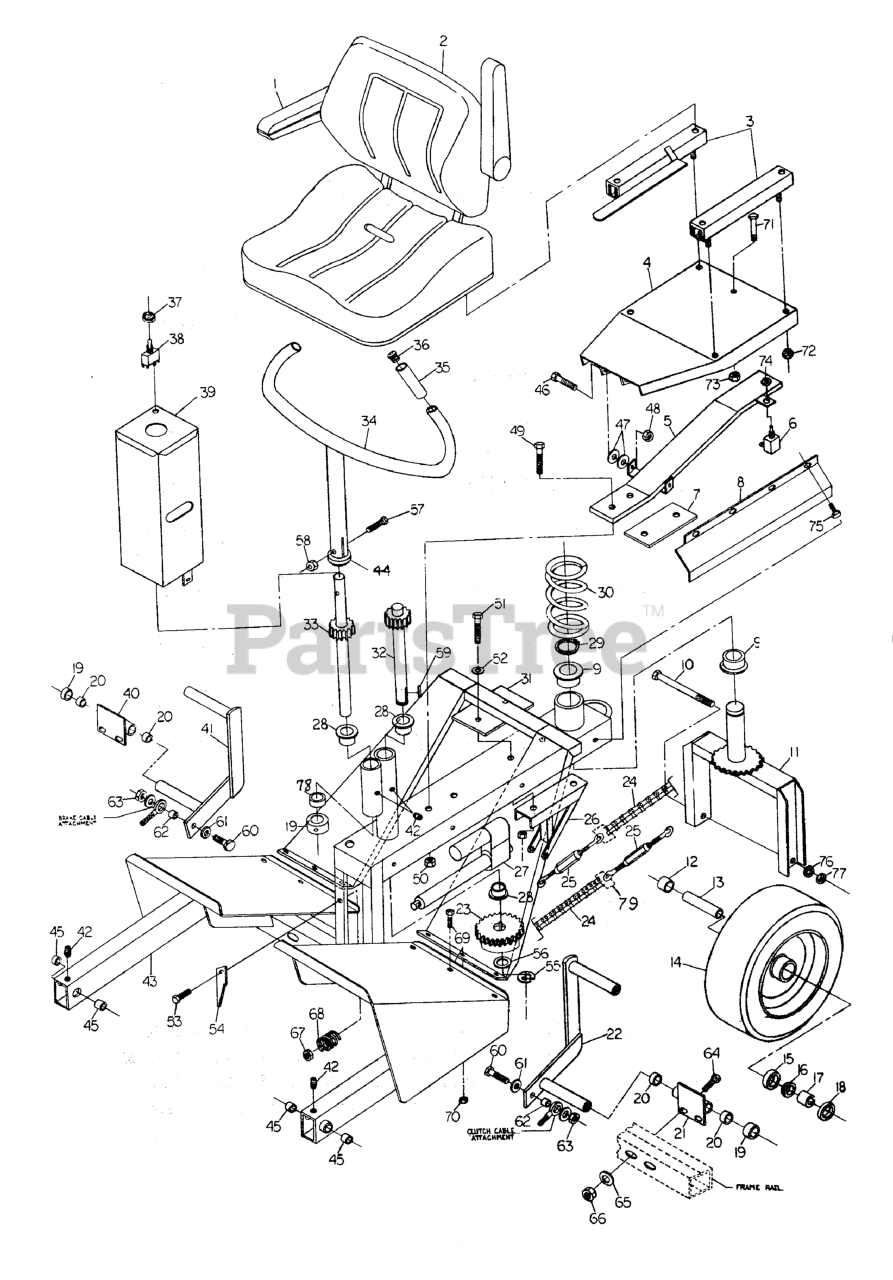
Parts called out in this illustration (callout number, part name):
1	Arm Rest (Left/Right Interchangeable)
3	SEAT ADJUSTER RAILS (Set)
4	Seat Mounting Plate Weldment
5	Seat Spring Weldment
6	Seat Switch
7	SUPPORT, Seat Plate
8	Chain Guard Left
9	BUSHING, Flange
10	BOLT, 5/8-11 x 9-1/2
11	Steering Wheel Mount Weldment
12	SPACER, 1.00 x 1.25 x 1.53
13	Steering Wheel Sleeve
14	Steering Tire Assembly
14	Tire Only
14	Rim Only
15	BEARING CUP
16	BEARING, Tapered Roller
17	Steering Tire Spacer
18	GREASE SEAL
19	COLLAR, 3/4" Set
20	BUSHING
21	Clutch Pedal Bracket Weldment
22	Clutch Pedal Weldment
23	40B 24 x 3/4 Sprocket
24	CHAIN, #40 Roller, 43 Links
25	Turnbuckle
26	Actuator Mount Weldment
27	Electric Actuator
28	BUSHING, Flange
29	SNAP RING, External
30	Compression Seat Spring
31	Actuator Mount Support
32	Steering Shaft Weldment
33	Steering Handle Shaft Weldment
34	Steering Handle Weldment
35	GRIP, Foam
36	End Plug
37	Toggle Boot
38	Toggle Switch
39	Steering Gear Guard
40	Brake Pedal Bracket
41	Brake Pedal Weldment
42	GREASE FITTING
43	Rider Frame Weldment
44	COLLAR, 1" Split
45	BUSHING
46	3/8-24 x 1-1/2 GD 8 Bolt
47	3/8 Flat Washer
48	3/8-24 Lock Nut
49	3/8-16 x 3-1/2 Bolt
50	3/8 Serrated Flange Nut
51	3/8-16 x 3-1/2 Bolt
52	3/8 Flat Washer
53	5/8-18 x 2 Bolt
54	Brake Lever
55	C-CLIP
56	3/4 Washer
57	3/8-16 x 1-1/2 GD 5 Bolt
58	3/8 Lock Nut
59	KEY, 3/16 SQ. X 7/8
60	1/4-20 x 1-1/2 GD 8 Bolt
61	1/4 Flat Washer
62	SPACER, .26 X .38 X .50
63	1/4 Lock Nut
64	5/16-18 x 2-1/2 GD 5 Bolt
65	5/16 Flat Washer
66	5/16-18 Serrated Flange Nut
67	5/16 Lock Nut
68	SPRING, Compression
69	5/16-18 x 1 GD 5 Hex Head Cap Screw
70	5/16 Serrated Flange Nut
71	5/16-18 x 6 GD 5 Bolt
72	5/16 Serrated Flange Nut
73	5/16 Lock Nut
74	7/16-20 Nut
75	1/4-20 x 5/8 GD 5 Bolt
76	5/8 Lock Washer
77	5/8 Lock Nut
78	BUSHING, Brass
79	CONNECTOR, #40 Chain Link
